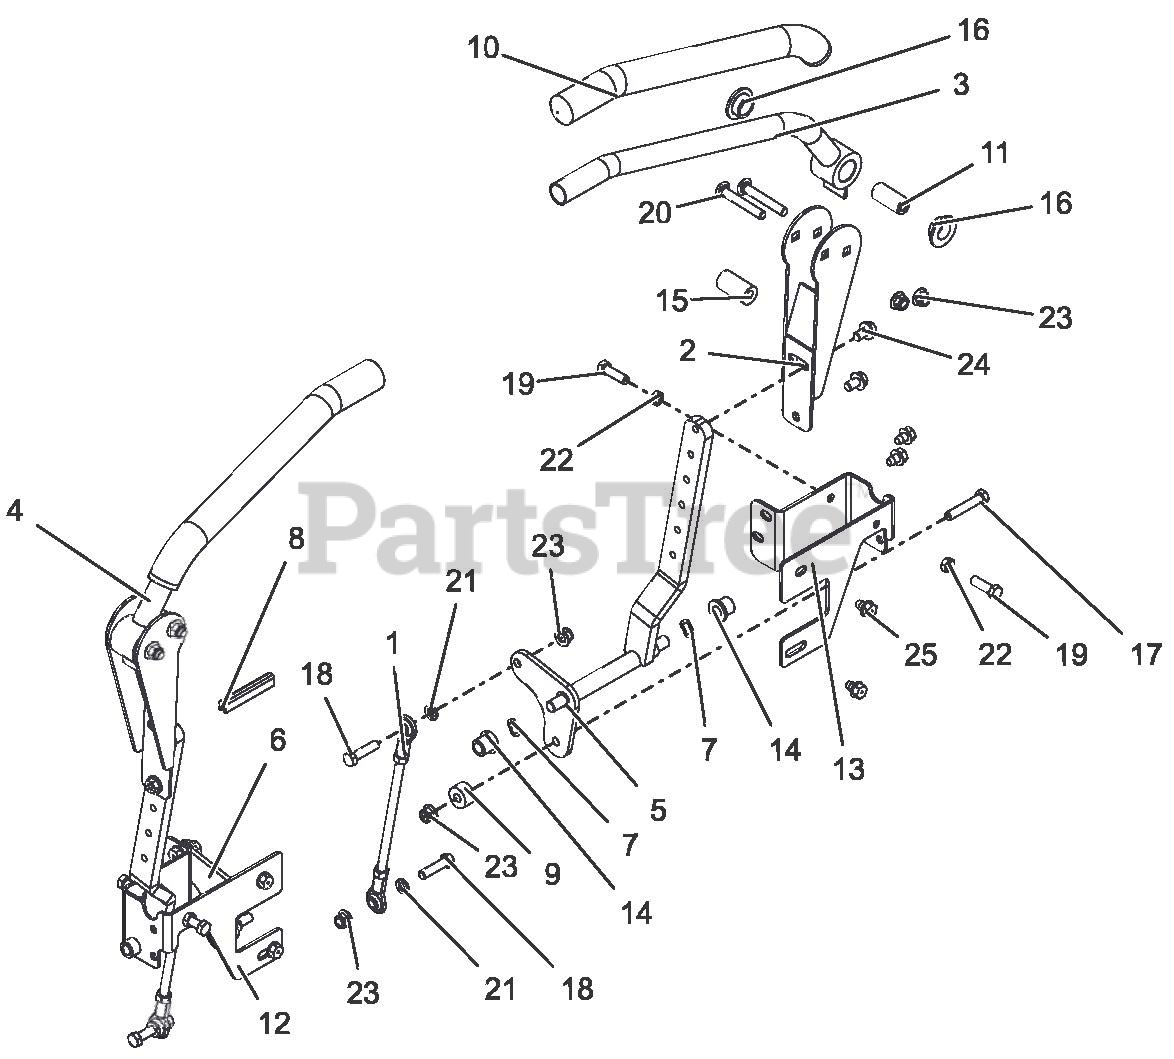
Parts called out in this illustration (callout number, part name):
1	ASM, STEERING LINKAGE
2	WLDMT, UPPER ADJUSTABLE CONTROL ARM
3	WLDMT, LH CONTROL HANDLE
4	WLDMT, RH CONTROL HANDLE
5	WLDMT, LH LOWER CONTROL ARM
6	WLDMT, RH LOWER CONTROL ARM
7	WAVE WASHER .531 X .781 X .125 FH
8	STRIP, COWL - 1.50 LG
9	SPACER .390 X 1.000 X .562
10	GRIP, HANDLEBAR
11	SPCR, STEERING ARM
12	BRKT, RH HD STEERING STOP
13	BRKT, LH HD STEERING STOP
14	BSHG-FLG .500 X .750 X .750 X .125
15	BSHG, ECCENTRIC .328 X .750 X 1.625
16	BSHG, FLANGE .762 X 1.48 X .44 NYLON
17	BLT-HEX .38-16 X 2.00 FTH GR5 YWZC
18	BLT-HEX .38-16 X 1.50 GR5 YWZC
19	BLT-HEX .38-16 X 1.25 GR5 YWZC
20	BLT-RDHDSQNK .38*16 X 2.50 GR5YZ
21	WSHR-LK .38 X .094 REG YWZC
22	NUT, JAM .375-16 YWZC
23	NUT-LK-NYL-FLG .38-16 YWZC
24	BLT-SERHFWH .38-16 X .62 YWZC
25	SCR-TAP .38-16 X .50 HWH TR YWZ
